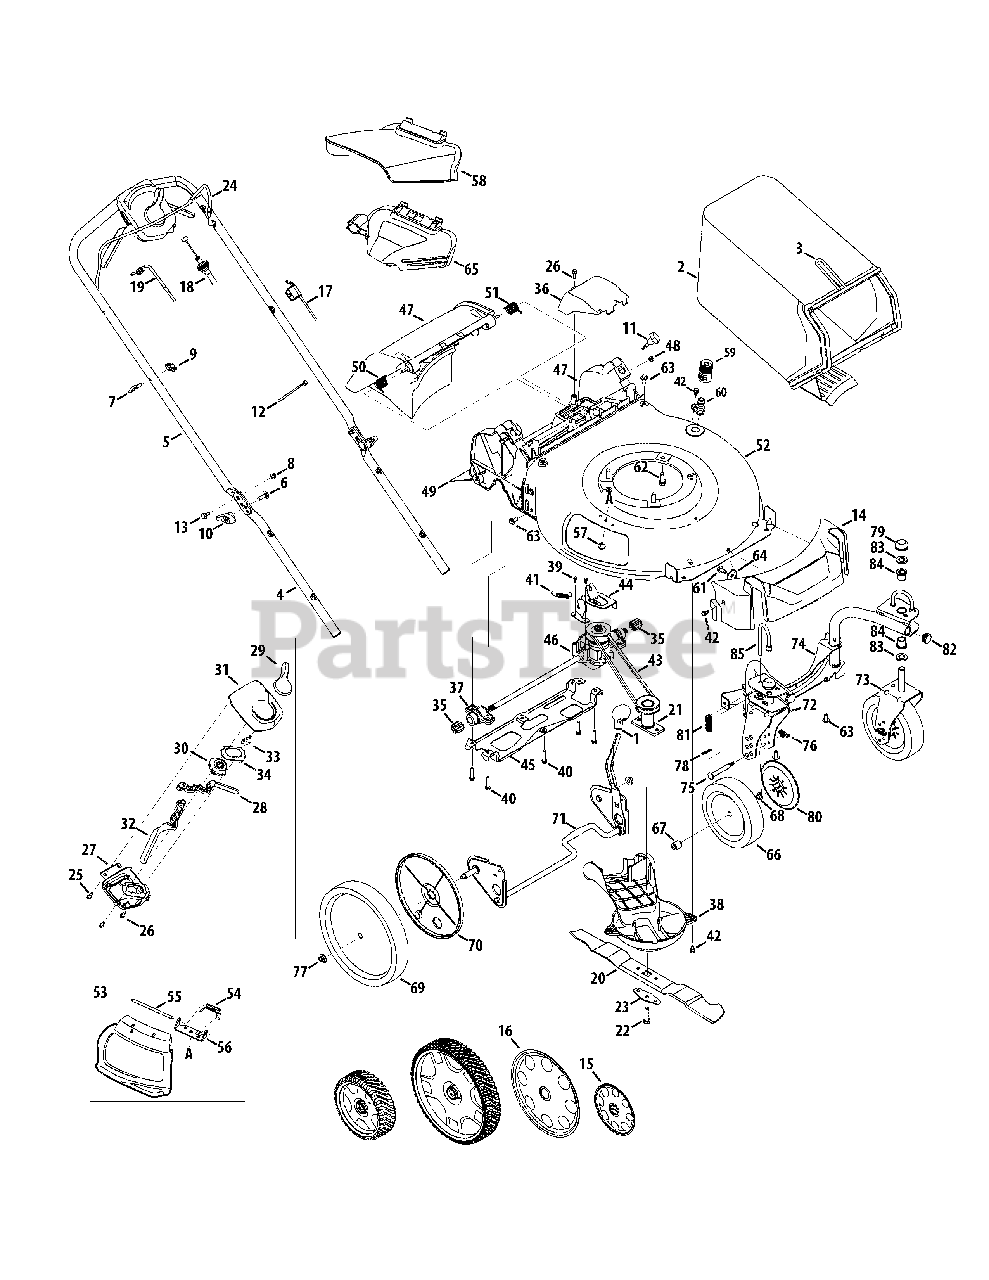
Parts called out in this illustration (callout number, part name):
1	Adjustment Lever Knob
3	Grass Catcher Frame
4	Lower Handle
6	Carriage Screw ,5/16-18
7	Rope Guide
8	Nut, Flange Lock, 1/4-20
12	Cable Tie
13	Sldr. Screw, .375 x .126 x 1/4-20
14	Front Cover
15	Hubcap, 7"
16	Hubcap, 11"
17	Control Cable
18	Drive Cable
19	Speed Adjustment Cable
20	Mulching Blade
21	Blade Adapter
22	Screw, 3/8-24 x 1.50
23	Blade Bell Support
25	Scr., Shldr, 1/4-15 x .970
26	Screw, 1/4-15 x .750
27	Lower Housing
28	Control Lever LH
29	Speed Select Lever
30	Speed Adjust Actuator
31	Upper Housing
32	Control Lever RH
34	Cable Adjust Plate
35	Spur Gear, 9T
36	Transmission Cover
37	Bearing Assembly
38	Engine Baffle
39	Screw, Hex Washer, .159 x .43
40	Screw, 1/4-15 x 1.25
41	Exten. Spring, 2.405
42	Shoulder Screw, 1/4-20 x 0.50
44	Transmission Bracket
45	Rear Support Bracket
46	Transmission Assembly
47	Rear Discharge Door Assembly
48	Nut, Sq., 1/4-20
49	Trailing Shield
50	Torsion Spring - RH
51	Torsion Spring - LH
53	Mulch Plug (Incl. 54-56)
54	Torsion Spring
56	Chute Deflector Bracket
57	Screw, 1/4-20 x .500
58	Side Discharge Chute
59	Water Nozzle Adapter
60	Water Nozzle
61	Self Tapping Screw, 5/16-18 x .750
62	Screw, 3/8-16 x 1.00
63	Screw, 5/16-14 x .750
64	Washer, Flat, .330 x 1.25 x .06
65	Chute Blower
66	Front Wheel, 7 x 2
67	Caster Hub, Long
68	Caster Hub, Short
69	Rear Wheel
70	Wheel Dust Cover
71	Rear Axle Assembly
72	Caster Bracket Assembly, RH
73	Caster Bracket Assembly, LH
74	Caster Bracket Assembly
75	Caster Axle, .374 Dia. x 2.59
76	Wing Nut, 1/4-20 w/Bell Washer
77	Flange Lock Nut, 3/8-16
78	Cotter Pin, .072 Dia. x 1.13 Lg.
79	Push Cap, 5/8
80	Dust Cover, 7"
81	Compr. Sprng., .531 OD x 1.75 Lg
83	Flat Washer, .640 x 1.12 x .125
84	Flange Bearing, .631 ID
85	Lock Pin: Front Wheel
